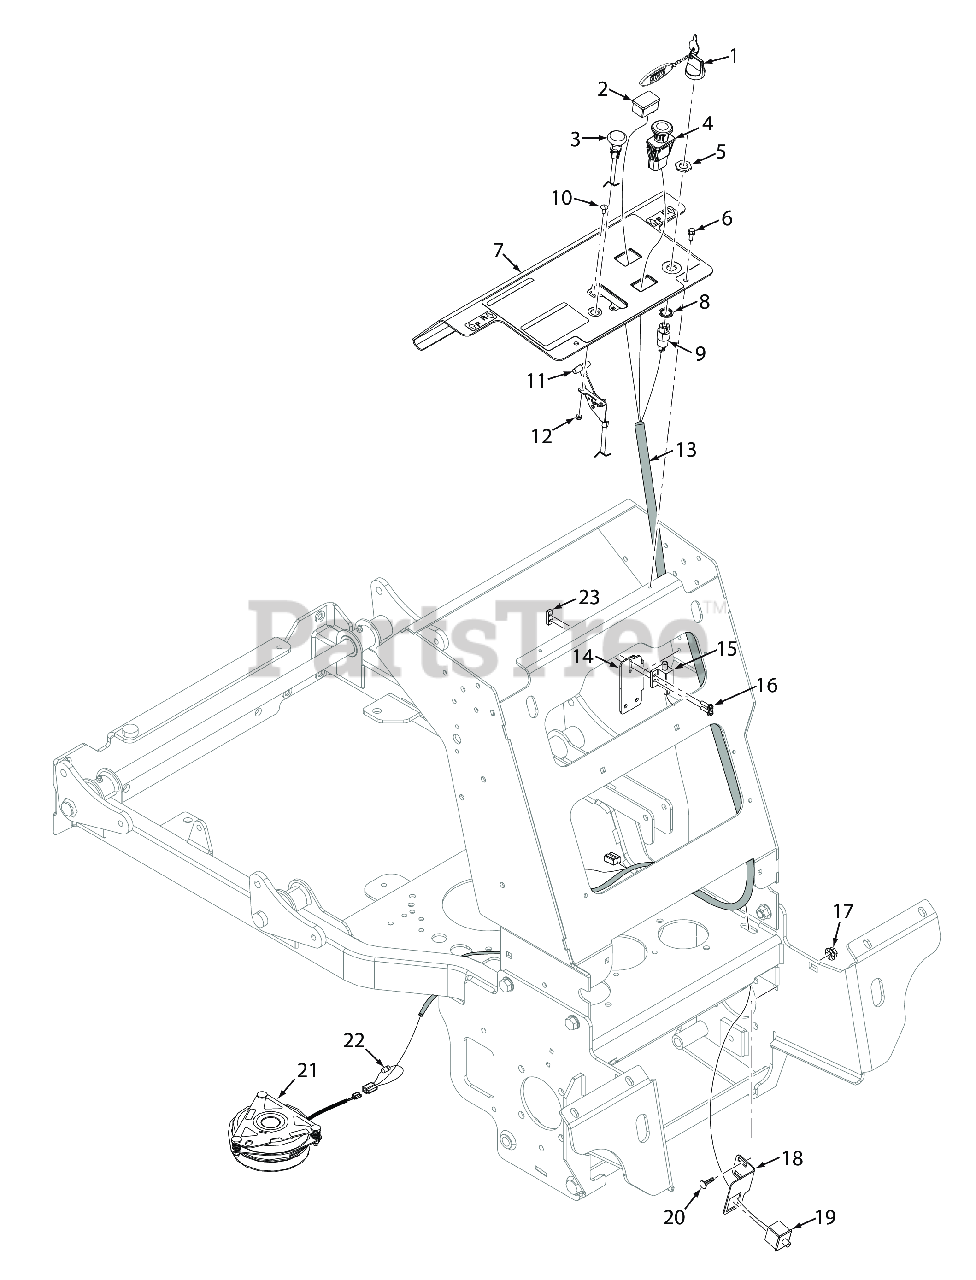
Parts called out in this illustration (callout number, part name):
1	Key, Assembly w/Fob
2	Hour Meter
3	Choke Control (excludes EFI models)
4	Switch, PTO - 10 Amp
5	Nut, 5/8-32 Special
6	Screw, Self-Tapping 1/4-20 x 3/4
7	Instrument Panel w/Decal - SVRII36
8	LOCK WASHER, 5/8" INTERNAL TOOTH
9	KEY SWITCH, MANUAL SRT.(INCL. HWD)
10	Bolt, Carriage #10-24 x 1/2"
11	Throttle Control, SVR
12	Nut, Elastic Stop #10-24
13	Wire Harness, SVRII Recoil Start
14	Bracket, Neutral Switch
15	Switch, Interlock (see below)
16	Screw, Hex-Slotted Washer Head #10 32 x 3/4"
17	NUT, 1/4-20 SERRATED FLANGE HEX HEAD
18	Switch Bracket, OPC Switch -SVRII-36
19	Switch, Double Pole OPC - SVRII-36
20	Serr. Fl. Hex Head CPSCR, 1/4-20 x 3/4"
21	Clutch w/Tag GT2.5-FE02 (48 / 52)
22	Diode, 600V 6 Amp
23	Plate, Threaded
